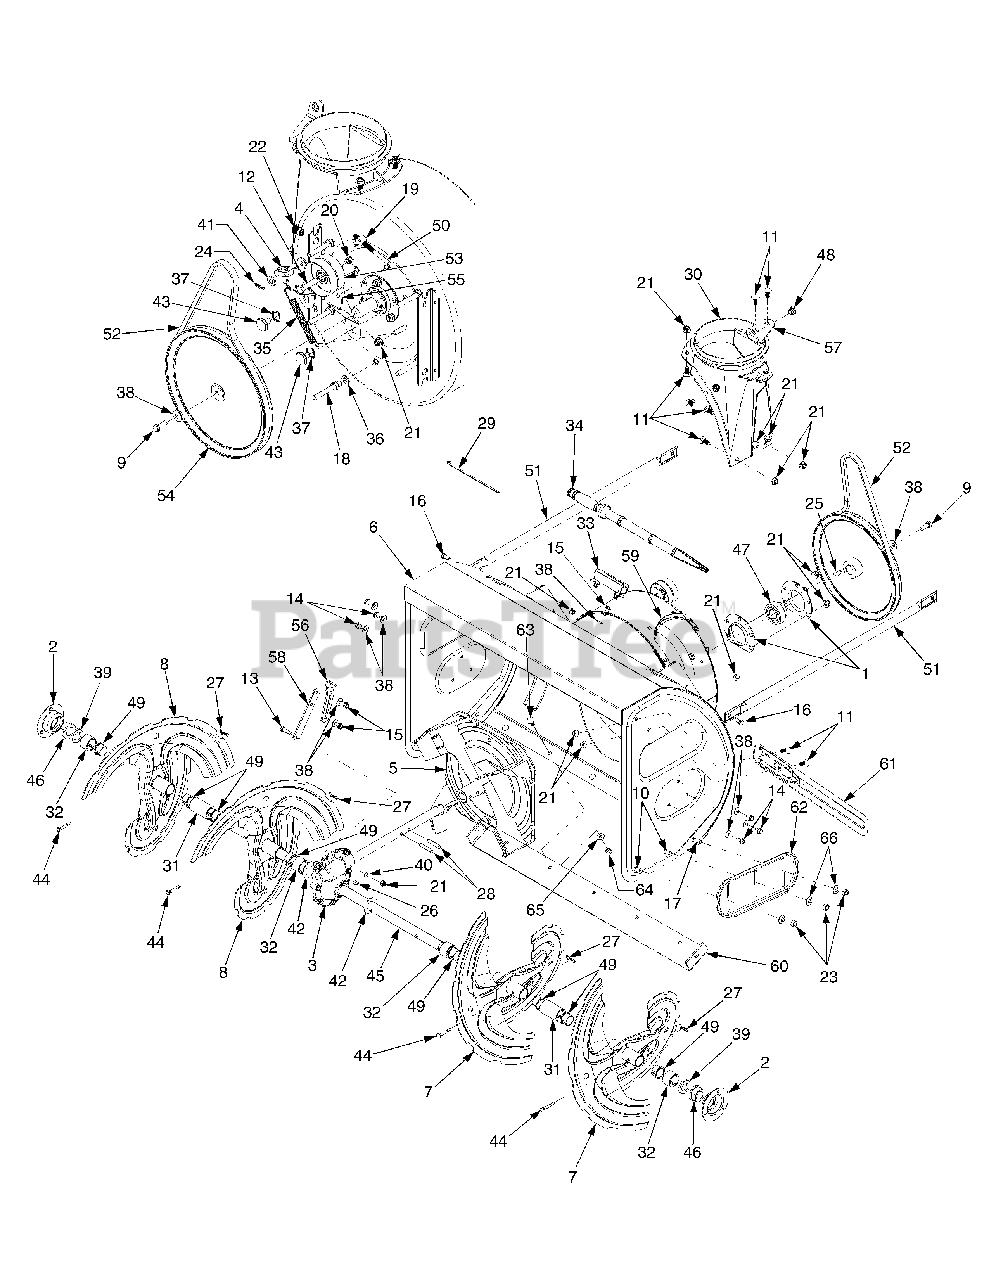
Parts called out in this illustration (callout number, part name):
1	Housing, Bearing
3	Gear Box Assembly, Auger
4	Bracket Assembly, Auger Brake ..
9	Screw, Hex Cap Lock, 5/16-18 x .875 GR5
10	Screw, Carr, Stnls Stl, 3/8-16 x .75
11	Screw, Carriage, 5/16-18 x .75
12	Screw, Hex Cap, 3/8-24 x 1.5 GR5
13	Screw, Hex Cap, 5/16-18 x 1.25 GR5
14	Screw, Hex Wash Hd. Tapp 5/16-18 x .625
15	Screw, Hex Wash Hd Tapp 5/16-18 x .75
16	Screw, Hex Cap, 5/16-18 x .75 GR5
17	Screw, Carr, Stnls Stll 3/8-16 x 1.0
18	Stud, 3/8-16 x 2.68
19	Ferrule
20	Nut, Hex Insert Jam Lock, 3/8-24 GR5
21	Nut, Hx Ins Flnge Lk, 5/16-18 GrF
22	Nut, Insert, 3/8-16
23	Nut, Hex, Stnls Stl, 3/8-16
24	Pin, Internal Cotter
25	Key, Hi Pro, 3/16 x 3/4
26	Key, Woodruff, #91: 1/4 x 3/4
27	Pin, Bowtie Cotter 28" & 33" S.T.
27	Pin, Bowtie Cotter 45" S.T.
28	Pin, Spirol, 5/16 x 1.75
29	Tie, Cable
30	Adapter, Chute, 6"
31	Spacer, 1.0 x 1.5 x 2.5Lg 33" S.T.
32	Spacer, 1.0 x 1.5 x 1.0Lg 28" & 33" S.T.
32	Spacer, 1.0 x 1.5 x 1.0 45" S.T.
33	Clip, Mounting
34	Tool, Cleanout
35	Spring, Extension
36	Washer, Lock, 3/8
37	Washer, Wave, .625 x .885 x .015
38	Washer, Belleville, .34 x .872 x .06
39	Spacer, 1.004 x 1.375 x .25
40	Washer, Spring, .317 x .625 x .02
41	Washer, Flat, .344 x .75 x .12
42	Washer, Flat, Hdn., 1.01 x 1.86 x .06
43	Screw, Shoulder, .625 x .17:3/8-16
44	Pin, Shear, .25 x 1.75 28" & 33" S.T.
44	Pin, Shear, .25 x 1.75 45" S.T.
45	Shaft, Spiral, 28" S.T.
45	Shaft, Spiral, 33" S.T.
45	Shaft, Spiral, 45" S.T.
46	Bearing, Flange w/Flats
47	Bearing, Self Aligning
48	Bushing, Nylon
49	Bushing, Flange, 28" & 33" S.T.
49	Bushing, Flange, 45" S.T.
50	Rod, Auger Idler
53	Pulley, Flat Idler, 2.75 OD
54	Pulley, Auger Drive, 10.0
60	Plate, Shave, Stnls Stl 33" S.T.
63	Screw, Carr., Stls Stl,5/16-18 x .75, 28" & 33" S.T.
63	Screw, Carr., Stls Stl,5/16-18 x .75, 45" S.T.
64	Nut, Hex, Stnls Stl, 28" & 33" S.T.
64	Nut, Hex, Stnls Stl, 45" S.T.
65	Washer, Bell, .34x.87x.06, Stnls Stl, 28" & 33" S.T.
65	Washer, Bell, .34x.87x.06, Stnls Stl, 45" S.T.
66	Washer, Bell, .37x.87x.06, Stnls Stl
